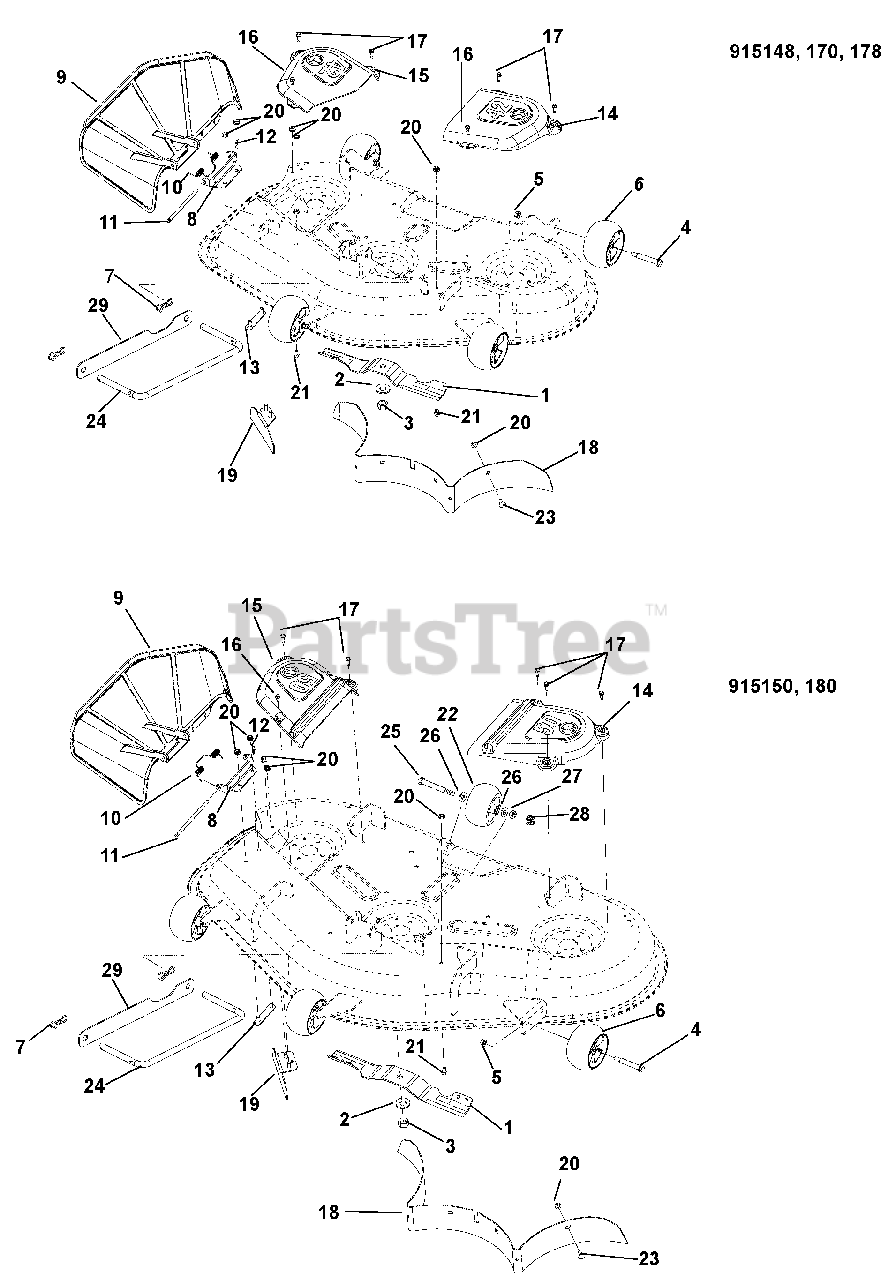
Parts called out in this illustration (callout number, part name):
1	Mower Blade, 14.83" (915148, 170, 178)
2	Washer, Bellville .63 x 1.625 x .14
3	Nut, Hex .62-18
4	Bolt, Shoulder .38-16 x 2.50 Hex Washer Head
5	Nut, Locking Top Flange .38-16
6	Anti-Scalp Wheel, 5 x 3 OS (915148, 170, 178)
7	Pin, Bow Tie Locking Cotter .091 x 1.875
8	Bracket, Discharge Chute Mount 42" (915148, 170, 178)
9	Discharge Chute – Molded
10	Spring, Torsion
11	Pin, 5/16 x 5.80"
12	Pin, Hair Internal .08 x .18 x 1.18
13	Weldment, Discharge Chute MT. Strap
14	Belt Cover, Left Hand 42" (915148, 170, 178)
15	Belt Cover, Right Hand 42" (915148, 170, 178)
16	Screw, Tapping .25-20 x .50 Hex Washer Head (915148, 170, 178)
17	Screw, Tapping .25-20 x .75 Hex Washer Head (915148, 170, 178)
18	Baffle, 42 Rear (915148, 170, 178)
19	Weldment – Baffle, Discharge 42" (915148, 170, 178)
20	Nut, Locking Top Flange .31-18
21	Bolt, Hex .31-18 x .50
22	Roller (915150, 180)
23	Bolt, Round Head Square Neck .31-18 x .75
24	Wireform, Drag Link
25	Bolt, Hex .38-16 x 3.50
26	Washer, Flat Steel .406 x .812 x .065 (915150, 180)
27	Nut, Locking Center Jam .375-16 (915150, 180)
28	Nut, Locking Nylon Flange .38-16 (915150, 180)
29	Strap, Drag Link
